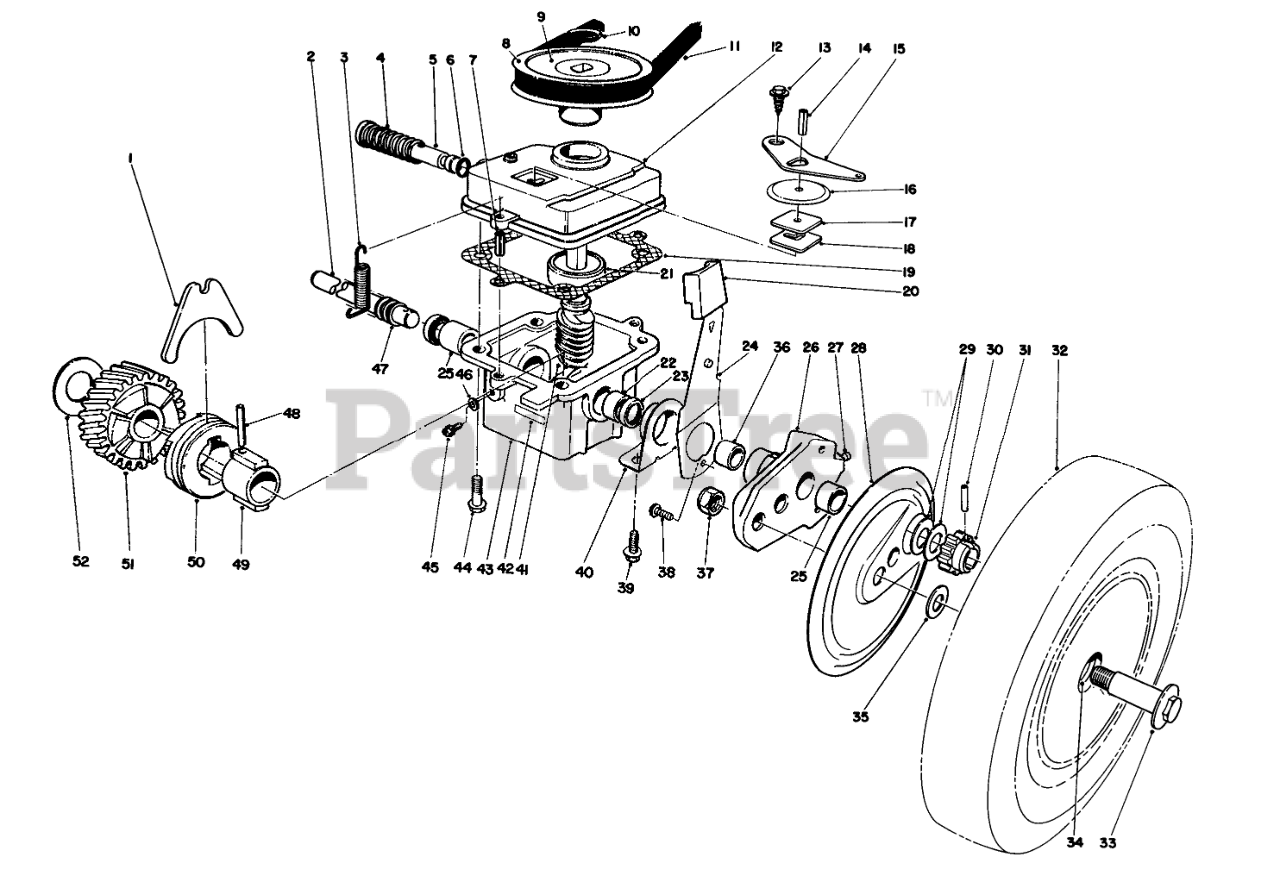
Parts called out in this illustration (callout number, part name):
1	SHIFTER FORK
2	DRIVE SHAFT
3	TENSION SPRING
4	SPRING
5	SHIFTER ROD
6	O-RING
7	3/16 X 1/2 ROLL PIN
8	PULLEY
9	DECAL
10	PUSH-ON 93-3236
11	V BELT
12	GEAR CASE COVER
13	Screw
14	SPIROL PIN H D
15	SHIFTER ARM
16	DUST COVER
17	DUST FILTER
18	LATCH PLATE
19	GASKET
20	KNOB-ARM
21	BEARING
22	BUSHING
23	SEAL-OIL
24	SPRING ARM ASSY-FRONT
25	BUSHING
26	Arm-Pivot (Incl. Ref. #25, 27 & 36)
27	FITTING-GREASE
28	WHEEL COVER
29	THRUST WASHER
30	Pin
31	PINION GEAR 15T
32	Wheel, Tire & Gear Assy (Incl. Ref. #34)
33	BOLT-WHEEL
34	BUSHING
35	WASHER
36	BUSHING
37	Nut
38	SCREW
39	SCREW-HWHTF
40	END CAP
41	Worm Shaft & Gear (Incl. Ref. #51)
42	DECAL
43	Gear Case (Incl. Ref. #22, 23 & 25)
44	Screw
45	NYLON SCREW
46	FILL PLUG GASKET
47	COVER-SHAFT, DRIVE
48	COIL PIN
49	SLEEVE
50	CLUTCH JAW
51	Gear-Helical
52	THRUST WASHER
